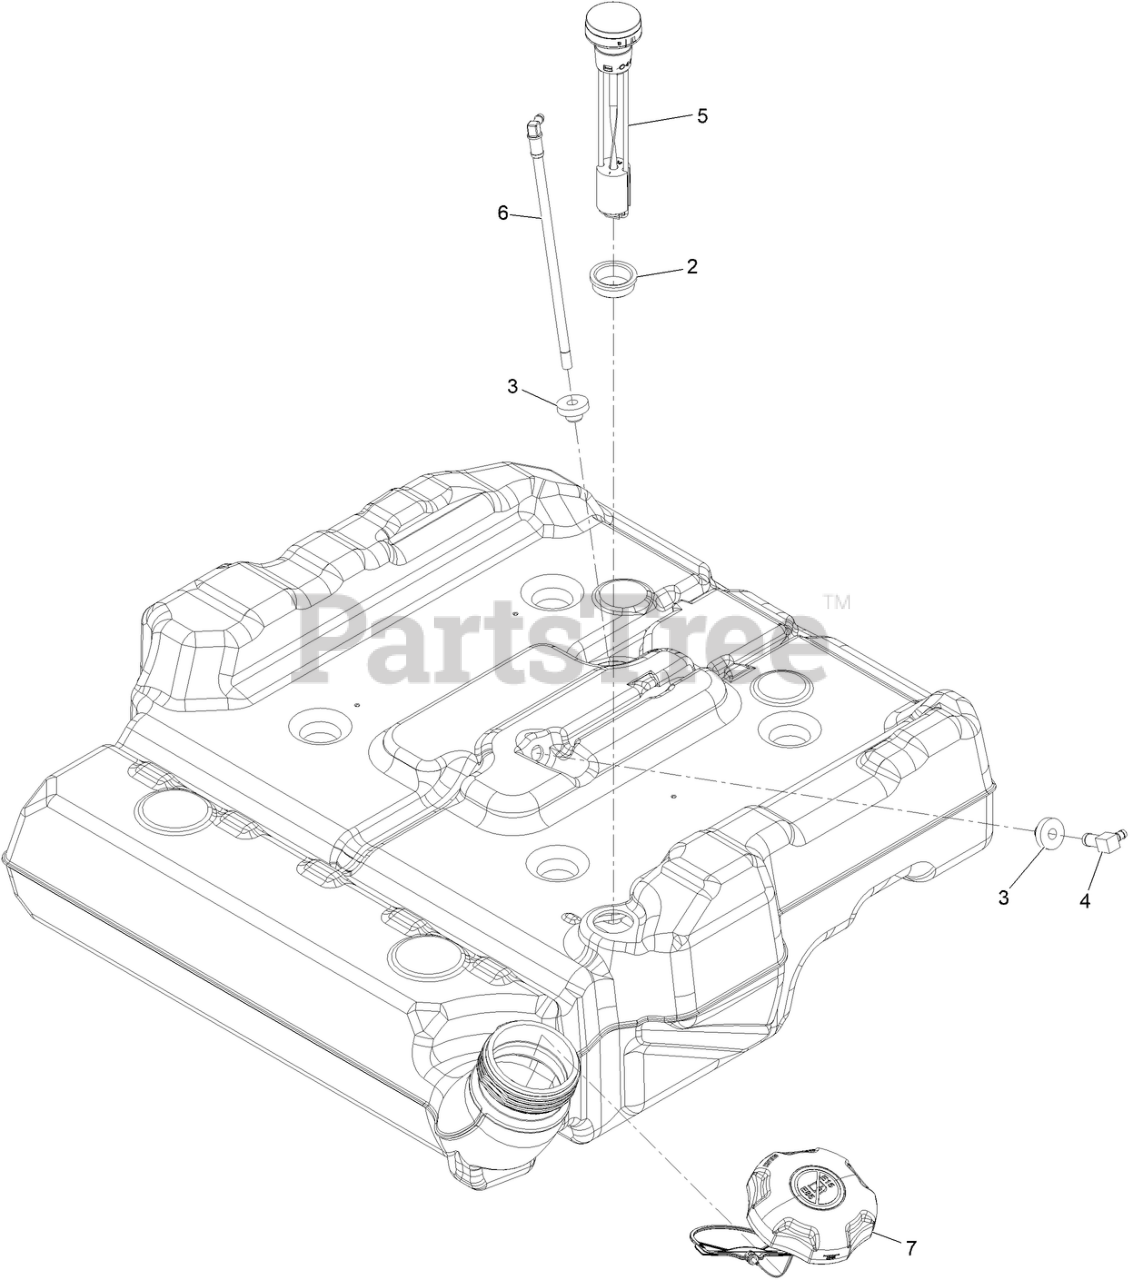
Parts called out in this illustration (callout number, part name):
2	Grommet-Fuel
3	BUSHING
4	Fiting-90 DEG
5	Guage, Fuel
6	Straw, Fuel
7	CAP-FUEL, RATCHETING
